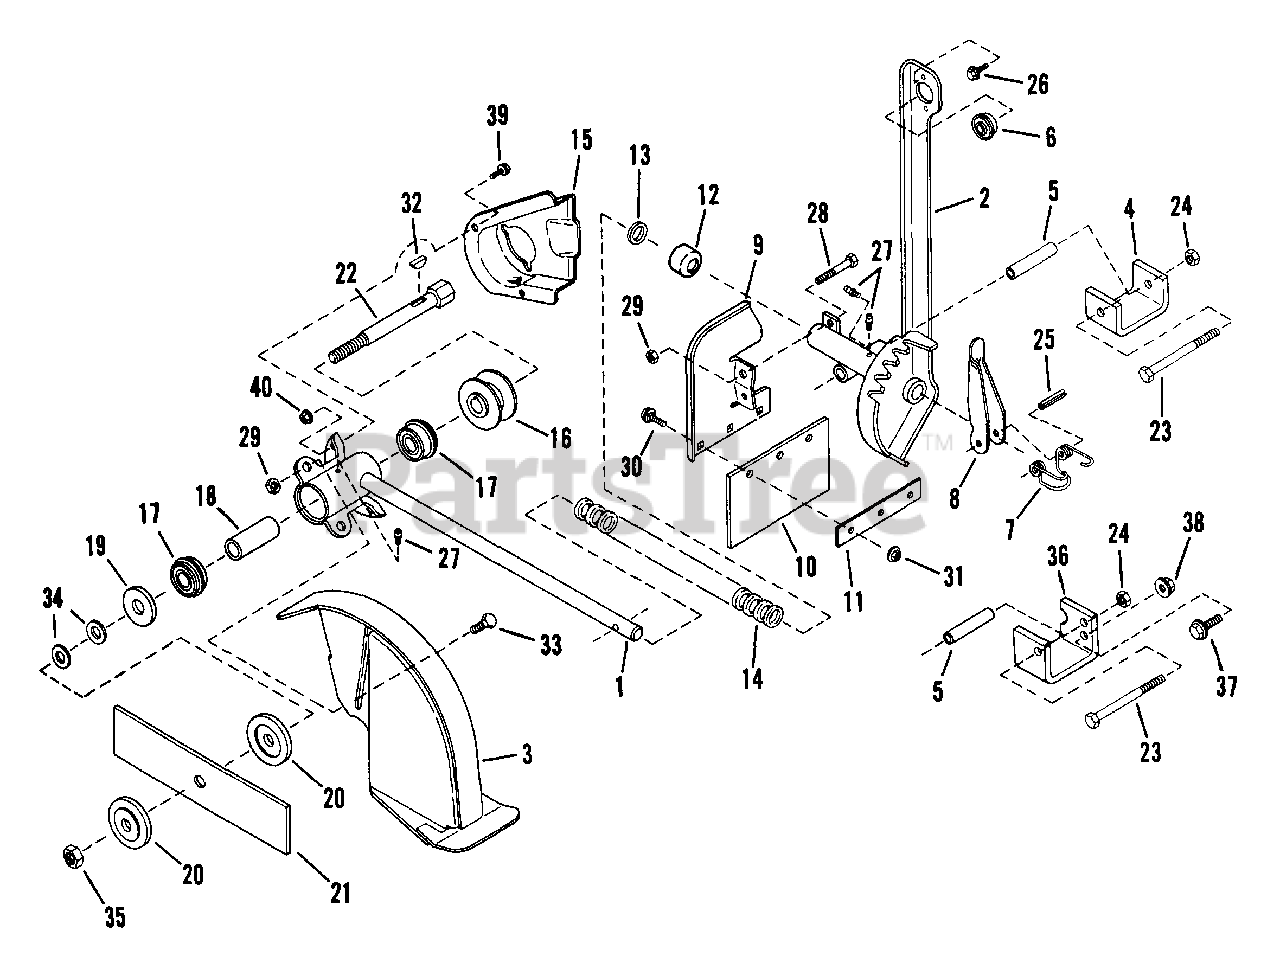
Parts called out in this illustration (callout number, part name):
1	STRUCTURE, Main Shaft
2	WELDMENT, Swivel Tube
3	STRUCTURE, Shield
4	BRACKET, Pivot
5	TUBE, Spanner
6	BEARING, Joint
7	SPRING, Swivel Stop
8	BRACKET, Lock
9	SHIELD, Debris
10	FLAP, Mud
12	COVER, Dust
13	SEAL, Felt
14	SPRING, Main
15	GUARD, Front Belt
16	PULLEY, Spindle
17	BEARING
19	CUP, Bearing
20	WASHER, Blade
21	BLADE, Edger
22	SHAFT, Spindle
23	SCREW, 3/8-16 x 3-1/4" Hex Cap
24	NUT, 3/8-16 Hex Lock
25	PIN, 1-3/4" Roll
26	SCREW, #10-32 x 1/4" Self-Tapping
27	LUBE FITTING, Straight (press-fit for .187 dia. Hole)
28	SCREW, 1/4-20 x 1-1/2" Hex Cap
29	NUT, 1/4-20 Hex Center Lock
30	BOLT, #10-24 x 1/2" Carriage
31	NUT, #10-24 Hex Flange Lock
32	KEY, (#6) 5/32 x 5/8" Woodruff
33	SCREW, 1/4-20 x 7/8" Hex Cap
34	WASHER, 1/2 Shim
35	NUT, 1/2-13 Hex Center Lock
36	BRACKET, Pivot
37	BOLT, 3/8-16 x 1" Hex Flange Lock
38	NUT,3/8-16 Hex Flange Lock
39	BOLT, 1/4-20 x 1/2" Hex Flange Lock
40	NUT, 1/4-20 Hex Flange Lock
